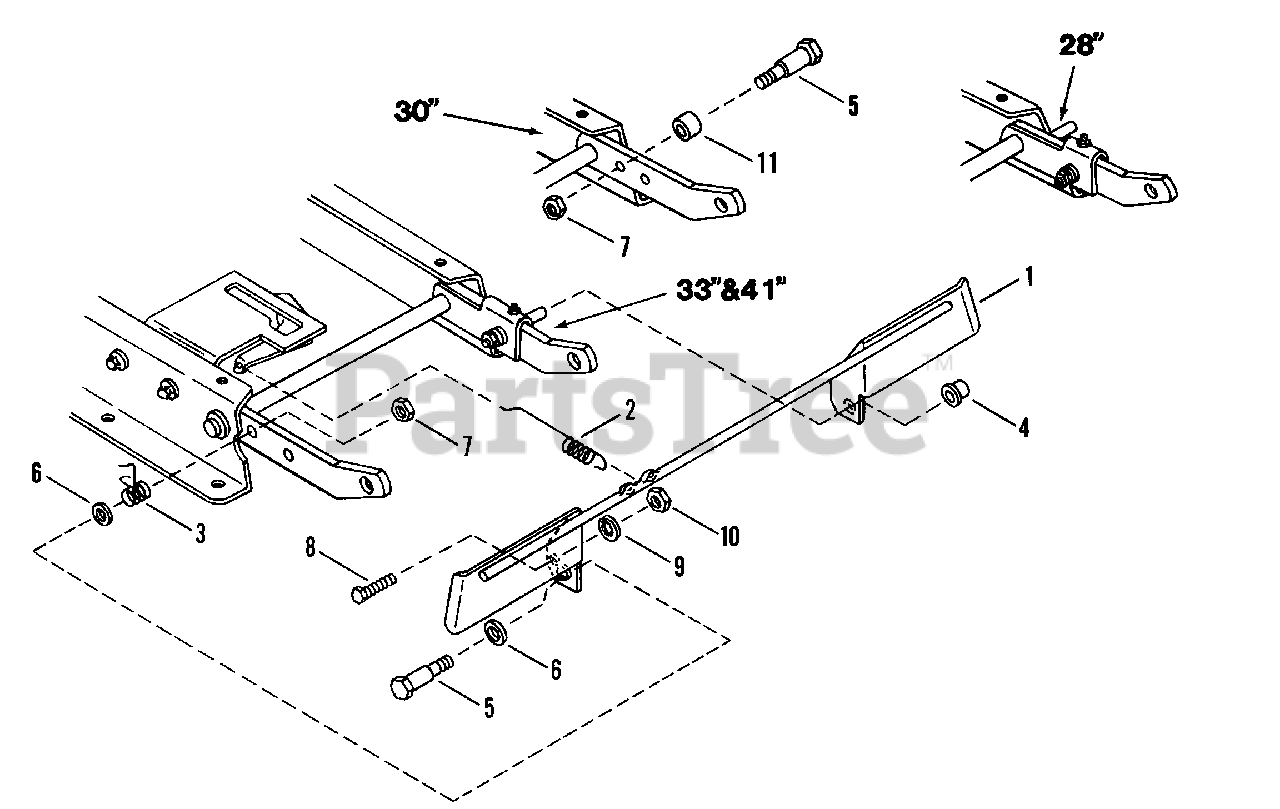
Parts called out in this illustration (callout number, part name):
1	PEDAL, Blade Stop Control
2	SPRING, Latching 33" & 41" Models
3	SPRING, Pedal
4	PUSH-NUT, 1/2"
5	BOLT, 3/8-24x1 3/4" Shoulder
6	WASHER, 1/2 SAE
7	NUT, 3/8-24 Hex
8	SCREW, 1/4-28x1" Hex Head Cap
9	WASHER, 1/4 Internal Tooth Lock
10	NUT, 1/4-28 Hex
11	SPACER
